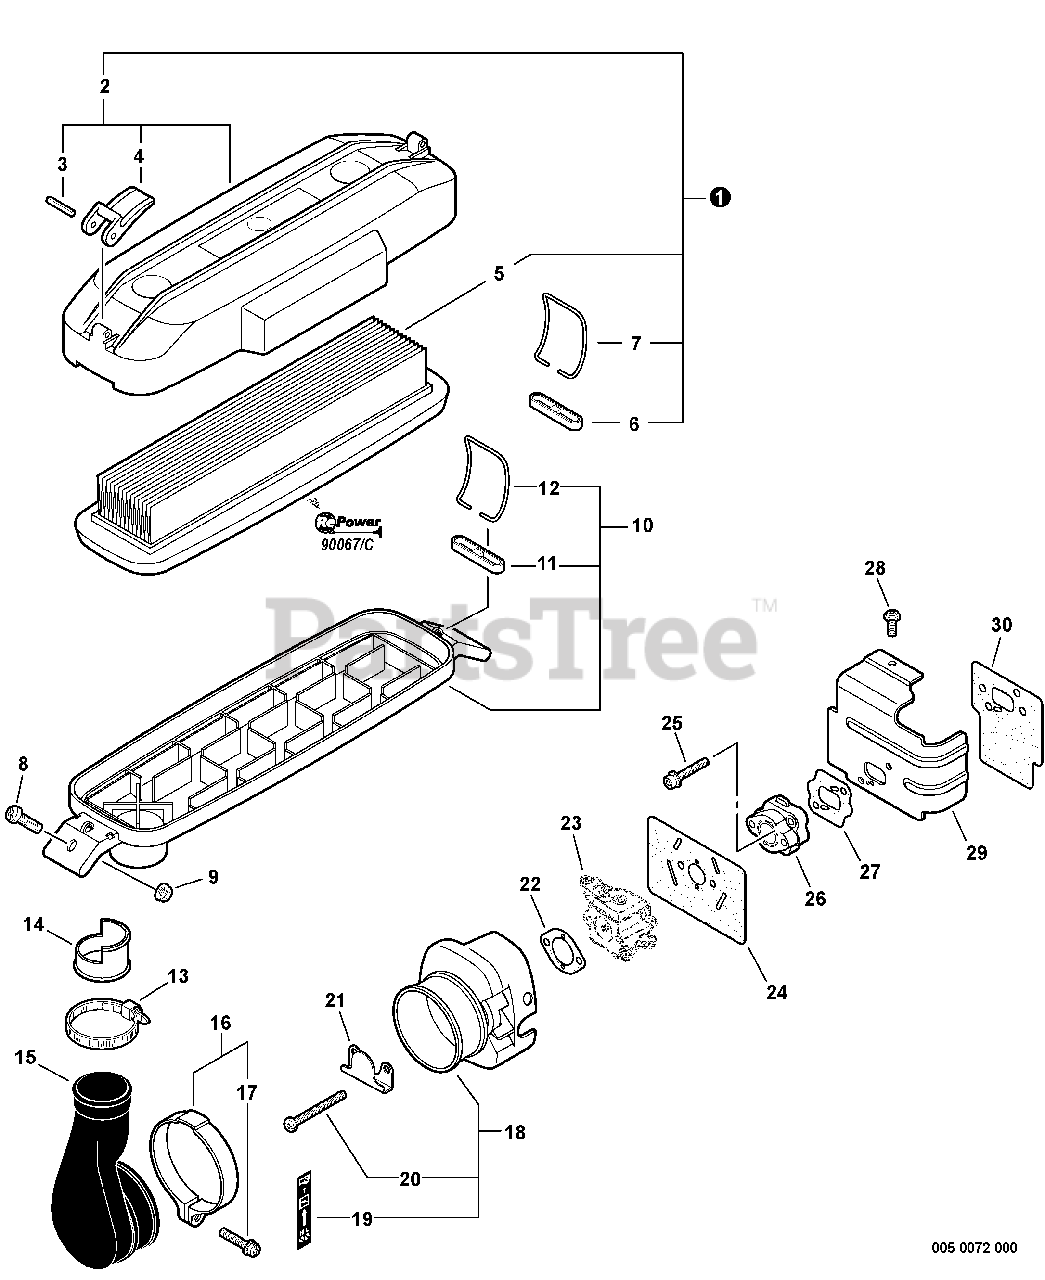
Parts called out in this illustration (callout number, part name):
1	AIR FILTER KIT
2	COVER ASSY, AIR FILTER
3	PIN, SPRING 3×25
5	FILTER, AIR
8	SCREW 5×14
9	NUT, FLANGE M5
10	CASE ASSY, AIR FILTER
14	COLLAR 27
15	ADAPTOR, INTAKE
16	CLAMP KIT
17	SCREW 5×25
18	BRACKET KIT, AIR FILTER
19	LABEL, CHOKE
20	SCREW 5×57
21	PLATE, PREVENT
22	GASKET, INTAKE
23	CARBURETOR
24	GASKET, INTAKE
25	BOLT 5×25
26	INSULATOR, INTAKE
27	GASKET, INTAKE
28	SCREW 5×10
29	COVER, CYLINDER
30	HEAT SHIELD, INTAKE
31	TUNE-UP KIT
